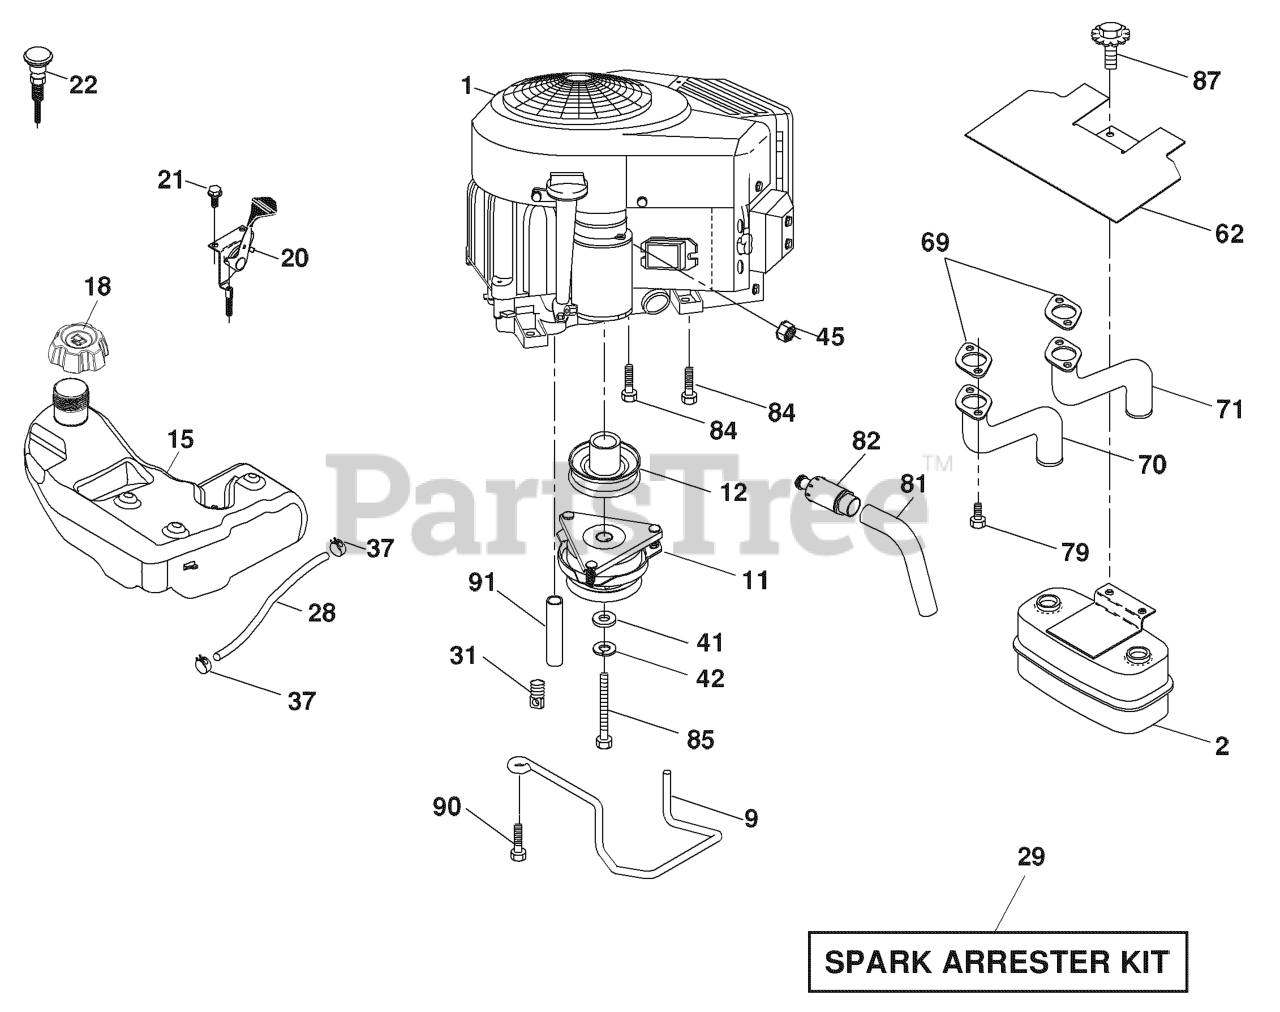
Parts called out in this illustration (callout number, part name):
2	MUFFLER.TWIN.CYL.LOW.TONE
9	KEEPER.BELT.ENGINE.4.2
11	CLUTCH MZ ZTR GT.48/54"1.125"
12	PULLEY ENGINE
15	TANK.FUEL.4GAL
18	CAP.FUEL.TANK.3"GREY
20	THROTTLE CABLE
21	SCREW
22	CONTROL.CHOKE.ERGO.PUSH-IN.BLA
28	LINE.FUEL.64"REAR.EMIS
29	KIT.SPARK ARRESTOR 794945 B&S
37	HOSE CLAMP
42	LOCKWASHER
45	NUT
62	RP SHIELD HEAT MUFFLER
69	GASKET.MUFFLER
70	RP.EXHAUST.TUBE.LH.BS/TWIN
71	EXHAUST.TUBE.RH.BS/TWIN
79	SCREW.SOCKET.HEAD.5/16-18
81	TUBE, DRAIN OIL ASM.
82	PLUG DRAIN OIL EASY
84	SCREW.3/8-16
85	BOLT HEX 7/16-20 X 3.75 GR. 5
87	BOLT.5/16-18UNCX1.W/SEMS.BLK
90	SCREW 3/8-16X1
91	BUSHING.1.375OD
